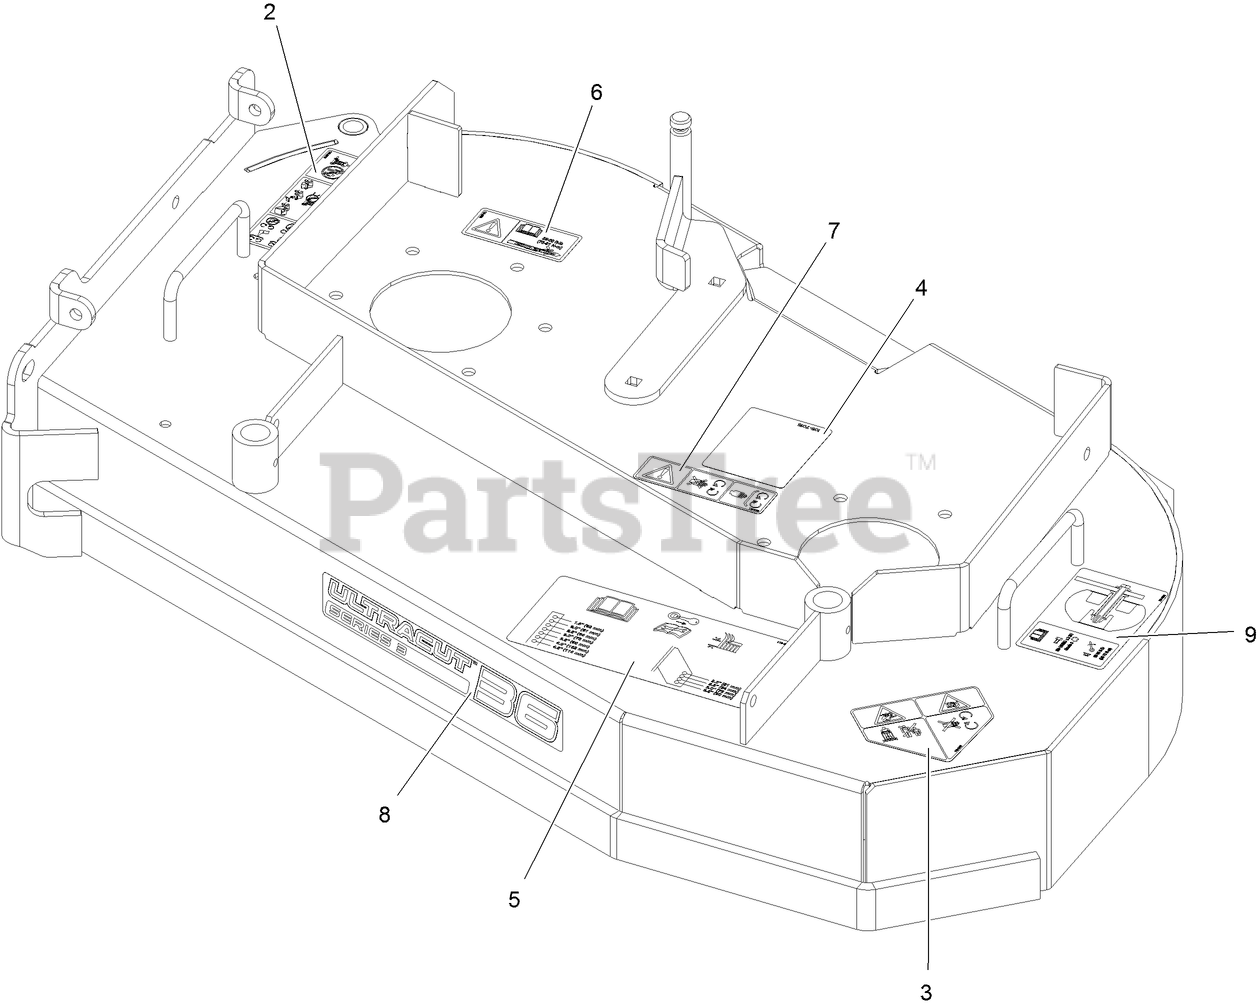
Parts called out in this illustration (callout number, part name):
2	DECAL-WARNING THROWN OBJ
3	DECAL-DANGER
4	DECAL-ROUTING, BELT
5	DECAL-ANTI-SCALP
6	DECAL-TORQUE, BOLT
7	DECAL-COVER, MISSING
8	DECAL-ULTRACUT 36 SERIES 3
9	DECAL-ROLLER MOUNTING
